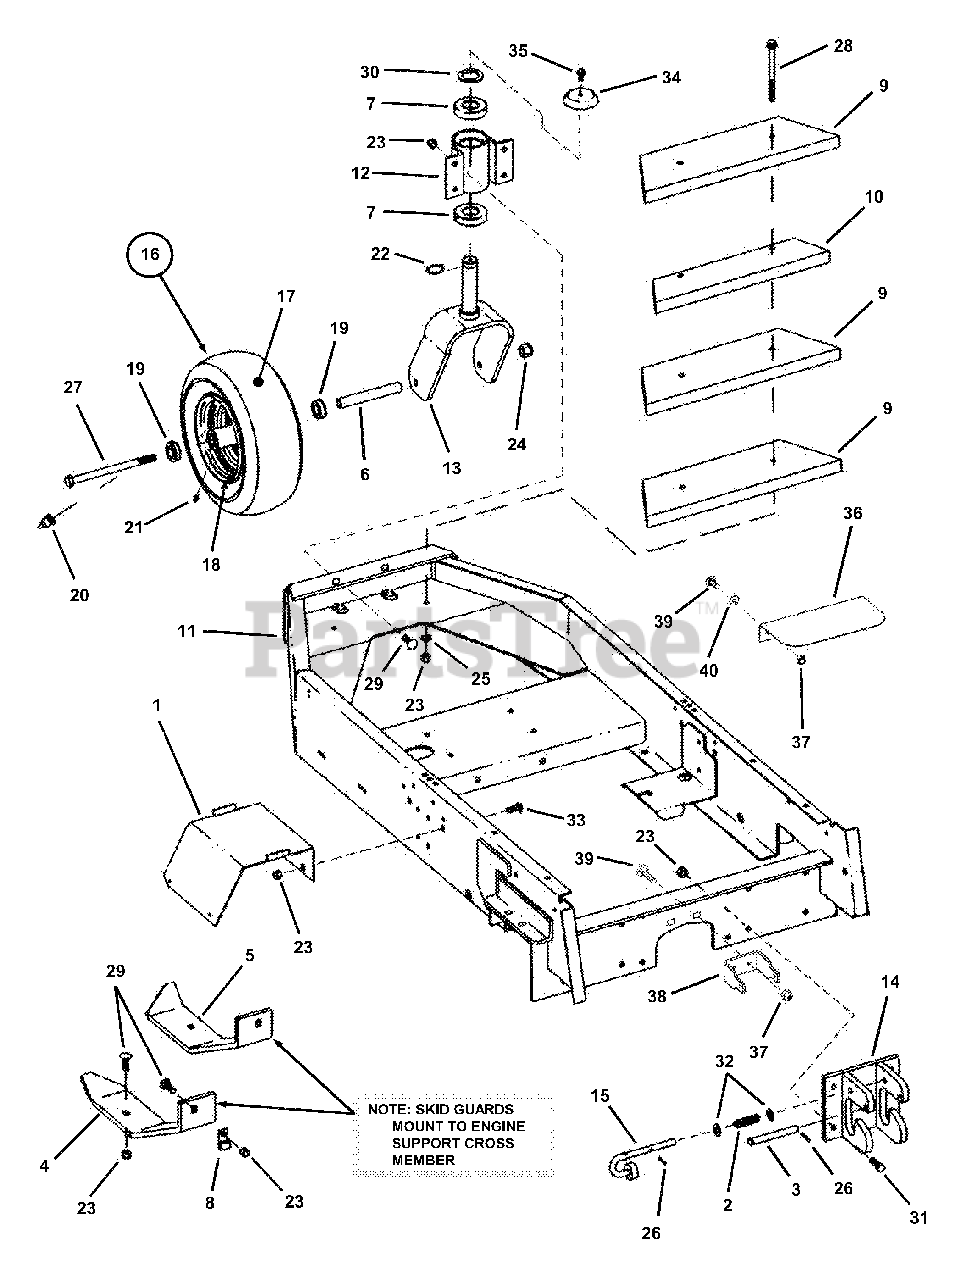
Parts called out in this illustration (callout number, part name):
1	BRACKET, Battery Support
2	SPRING
3	PIN, Clevis 1/2 x 4"
4	SKID GUARD, R.H.
5	SKID GUARD L.H.
6	SLEEVE, Axle
7	BEARING, 30mm x 62mm
8	J-CLIP, Open Cushioned
9	COUNTERWEIGHT, Large
10	COUNTERWEIGHT, Small
11	CHASSIS, Lower
12	WELDMENT, Caster Support
13	WELDMENT, Caster Yoke
14	WELDMENT, Hitch Plate
15	WELDMENT, Hitch Pin
16	ASSEMBLY, Tire & Rim
17	TIRE, 13 x 5.00-6 4 Ply
19	BEARING
20	VALVE, Air
21	FITTING, Lube
22	RING, 1-3/16" External Retaining
23	NUT, 3/8-16 HEX NYLON LOCK
24	NUT, 1/2-13 Nyloc
25	WASHER, 3/8" Flat
26	PIN, Cotter, 1/8 x 3/4"
27	BOLT, HEX, 1/2-13 X 7, GD 8, YZ
28	BOLT, 3/8-16 x 4-3/4", Grade 5
29	BOLT, 3/8-16 x 1-1/4", Carriage, Grade 5
30	WASHER, 1-1/4 I.D. x 1-7/8 O.D. Flat
31	BOLT, 3/8-16 X 1-1/4" GD5 CZ
32	WASHER, 15/32 I.D. x 15/16" O.D. Flat
33	BOLT, 3/8-16 x 1" Carriage, Grade 5
34	CAP, Caster Shaft
35	SCREW, 5/16-18 x 5/8" Self Tapping
36	SHIELD, Grass
37	NUT, 3/8-16 HEX NYLON LOCK
38	BRACKET, Cylinder
39	BOLT, 3/8-16 x 1-1/4" Short Neck Carriage, Grade 5
40	RETAINER, 3/8" Bolt
